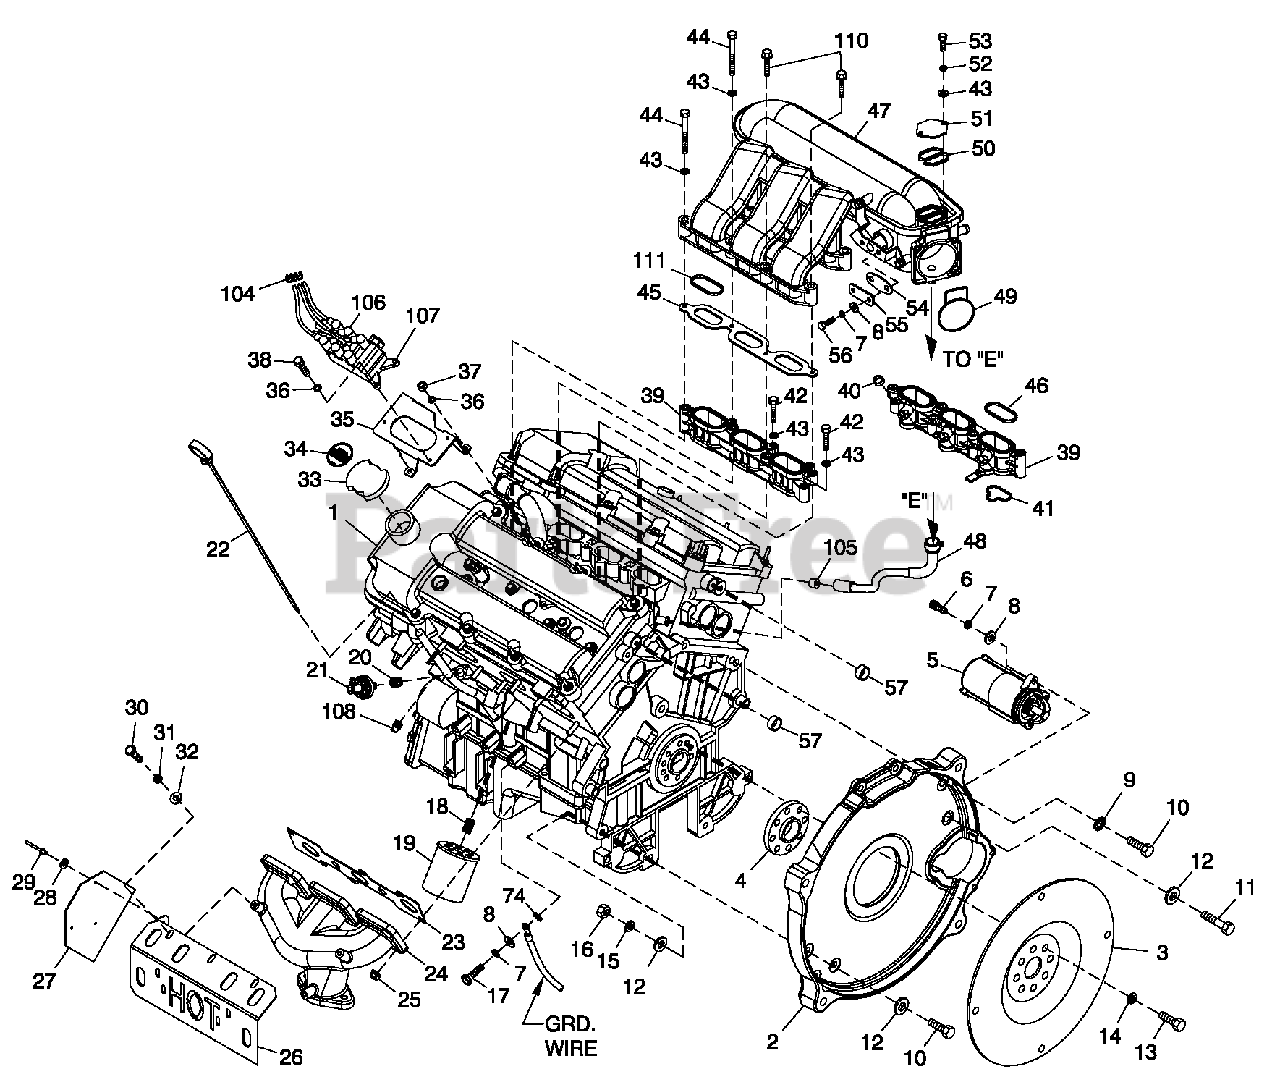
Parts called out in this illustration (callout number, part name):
1	ENGINE 3.0LRWDG14 MAKE
2	ADAPTER ENGINE
3	FLEX PLATE 2 POLE
4	SPACER FLEX PLATE
5	STARTER MOTOR 12V
6	SCREWS HC M8-1.25 X 30 G12.9
7	WASHER LOCK M8-5/16
8	WASHER FLAT 5/16-M8 ZINC
9	WASHER SHAKEPROOF EXT 7/16 STL
10	SCREW HHC M10-1.5X 45 G8.8 FT
11	SCREW HHC M10-1.5X 60 G8.8
12	WASHER FLAT 3/8-M10 ZINC
13	SCREW HHC M10-1.0X 25 G10.9
14	WASHER FLAT .45X1.00
15	WASHER LOCK M10
16	NUT HEXM10-1.5G8YELCHR
17	SCREW HHC M8-1.25X 25 G8.8
18	ADAPTER OIL FILTER 3.0L
19	OIL FILTER
20	BSHG RDCR HEX 3/8 TO 1/8 GALV
21	SWITCH OIL PRESSURE 10 PSI 2 POL
22	DIP STICK OIL 3.0L
23	GASKET EXHAUST
24	MANIFOLD EXHAUST LH
25	NUT HEX FLWH IZM8-1.25
26	HEAT SHIELD EXHAUST 3.0L
27	REFLECTIVE HEAT SHIELD 3.0L
28	WASHER FLAT #6 ZINC
29	RIVET POP.125X.400 AL
30	SCREW HHC 1/4-20 X 1/2 SS
31	WASHER LOCK 1/4-M6SS
32	WASHER FLAT 1/4 SS
33	OIL FILLER CAP 3.0L
34	DECAL REFER TO OWNERS MANUAL
35	BRACKET COIL
36	WASHER LOCK M5
37	NUT HEX M5-0.8 G8 CLEAR ZINC
38	SCREW HHC M5-0.8X 25G8.8
39	MANIFOLD INTAKE LOWER 3.0L
40	PLUG EXPANSION 14 OD
41	GASKET LOWER INTAKE BOTTOM
42	SCREW HHC M6-1.0X50G8.8
43	WASHER FLAT 1/4-M6 ZINC
44	SCREW HHC M6-1.0X 110 G8.8
45	PLATE, INTAKE 3.0L
46	GASKET LOWER INTAKE TOP
47	MANIFOLD INTAKE UPPER
48	ASSEMBLY HOSE PCV VALVE
49	GASKET INTAKE ADAPTER
50	GASKET IDLE AIR CONTRL ACT CVR
51	COVER IAC ACTUATOR
52	WASHER LOCK M6-1/4
53	SCREW HHC M6-1.0X 16 G8.8
54	EGR GASKET
55	COVEREGR
56	SCREW HHC M8-1.25X20G8.8
57	PLUG, EXPANSION 16MM
58	REWORK HARMONIC BAL 3.0L RWD
59	BELT SERPENTINE 71.04"
60	WATER PUMP 3.0L
61	HOSE WATER PUMP 3.0L
62	CLAMP HOSE #24 B1.06-2.00
63	REWORK BREAT HER TUBE 3.0L
64	SCREW HHC M8-1.25X65G8.8
65	PULLEY GROOVED ENGINE IDLER
66	SPACER IDLER PULLEY 3.0L
67	SCREW HHC M6-1.0X20G8.8
68	SENSOR CRANKSHAFT SPEED 3.0L
69	WELDMENT IDLER BRACKET 3.0L
70	BOLT HEX FLH DM8-1.25X28
71	SPACER .34X 1.00X.11 STL/ZC
72	SCREW HHC M8-1.25X35G8.8
73	SPARK PLUG (PLATINUM) .044 GAP
74	WASHERS HAKEPROOF EXT5/16STL
75	HARN ENG 3.0L G14 R-200 2P (NOT S HOWN)
76	NUT HEX M8-1.25 G8 CLEARZINC
77	BRACKET DC ALTERNATOR LOWER
78	BRACKET TENSIONER
79	ALTERNATOR DC W/OUT PULLEY
80	SPACER DC ALTERNATOR PULLEY
81	PULLEY 132 OD DC ALTERNATOR
82	SCREW HHC M10-1.5X25G8.8
83	BRACKET T HERMOSTAT 3.0L
84	NUT HEXM6X1.0G8YELCHR
85	CLAMP HOSE #28 1.32-2.25
86	HOSE UPPR RAD REAR
87	ADAPTER THERMOSTAT
88	GASKETTHERMOSTAT
89	MACHINING,THERMOSTAT ADPTR
90	THERMOSTAT 195 DEG
91	SWITCH HI-TEMP 245D X 3/8 NPT
92	WASHER LOCK M5
93	SCREWH HTT M5-0.8X10BP
94	SCREWH HC M8-1.25X80G8.8
95	BARBED STR1/2NPTX 3/4
96	CLAMP HOSE #10.56-1.06
97	HOSE COOL 3/4 ID 20R3 (22"LG)
98	HOSE OIL DRAIN ASSY 21"
99	CLAMP HOSE .38-.87
100	BARBEDEL 90 3/8 NPT X 3/8
101	ADAPTERM12-1.75X 3/8 NPT
102	WASHER NYLON .50 X .87 X .06
103	SCREW HHC M10-1.5X35G8.8
104	RETAINER SPARK PLUG WIRE
105	RESTRICTOR PCV
106	SPARK PLUG WIRE SET
107	COIL IGNITION
108	PLUG STD PIPE 3/8 COUNTERSUNK
109	MANIFOLD EXHAUST RH
110	SCREW HHC M6-1.0 X 50 G8.8 (INCL. WIT H I/N 47)
111	GASKET INTAKE MANIFOLD UP G3
